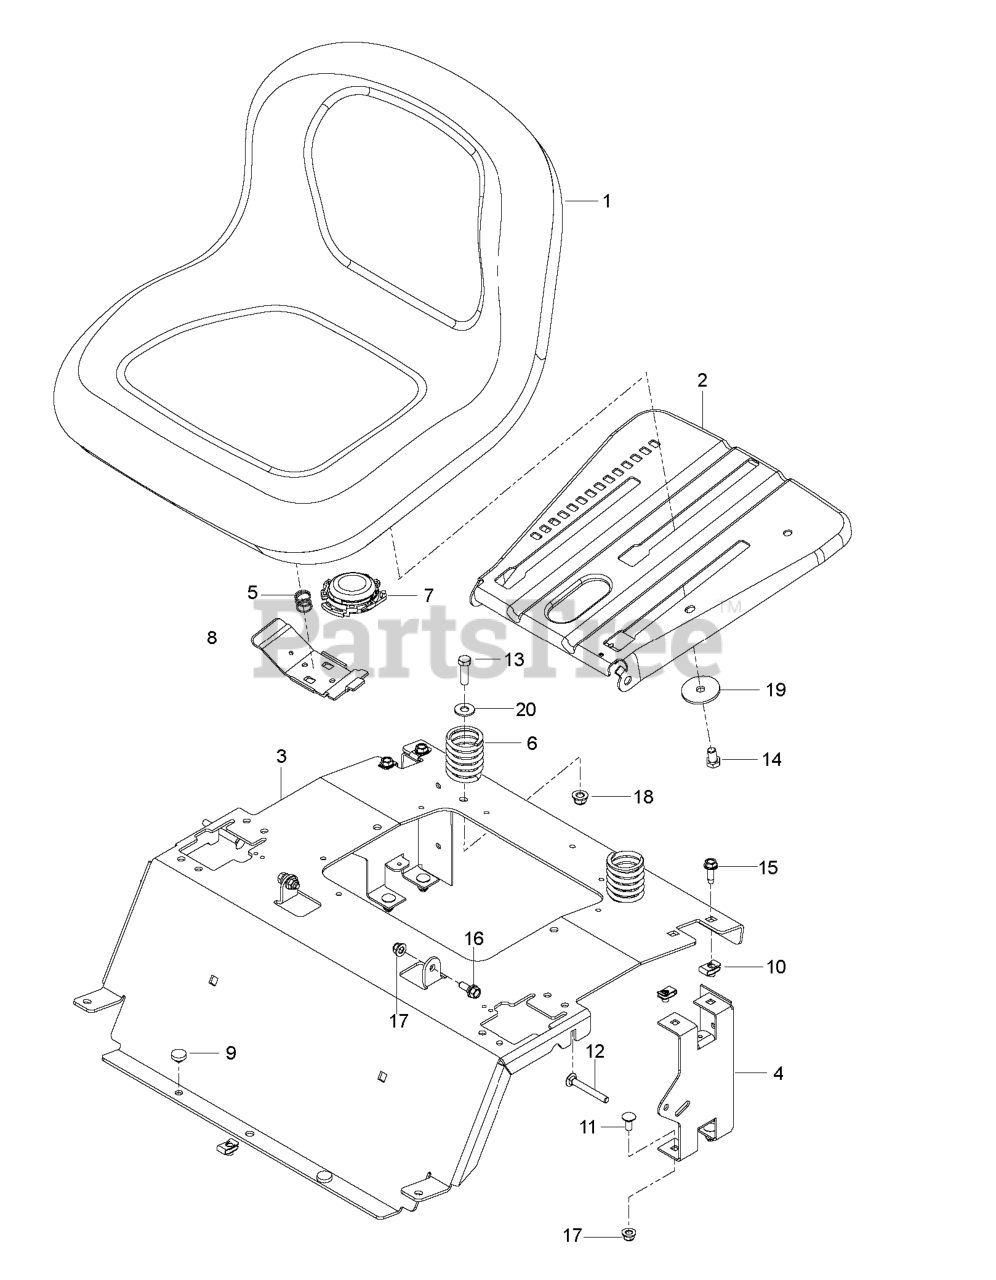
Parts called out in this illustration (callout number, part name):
1	SEAT.TH150.MS498.GRY.HUSQ.TEX
2	PAN.ASM.SEAT.3PT
3	SUPPORT SEAT ORANGE
4	SUPPORT REAR SEAT BLACK
5	SPRING.LATCH.SEAT.TEX
6	SPRING.COMPRESSION.SEAT.BLACK
7	SWITCH, SEAT N/C
8	HANDLE.SLIDE.SEAT.TEX.BLACK
9	GROMMET, BUMPER
10	U-CLIP 5/16-18 NUT RETAINER
11	RP BOLT 5/16-18 X3/4 ZN/YEL GR
12	RHSNB 5/16-18 X 2-1/2 GR5 ZD
13	BOLT
14	HCS 3/8-16 X 5/8 GR 5 ZD
15	SCREW.THDROL.5/16-18X3/4.TTY
16	BOLT, SHOULDER
17	5/16-18 NYLOC FLANGE NUT
18	NUT 3/8-16 HEX FLG NYLOC ZD
19	WASHER, 3/8 SPEC
20	RP WASHER 3/8 FLAT
